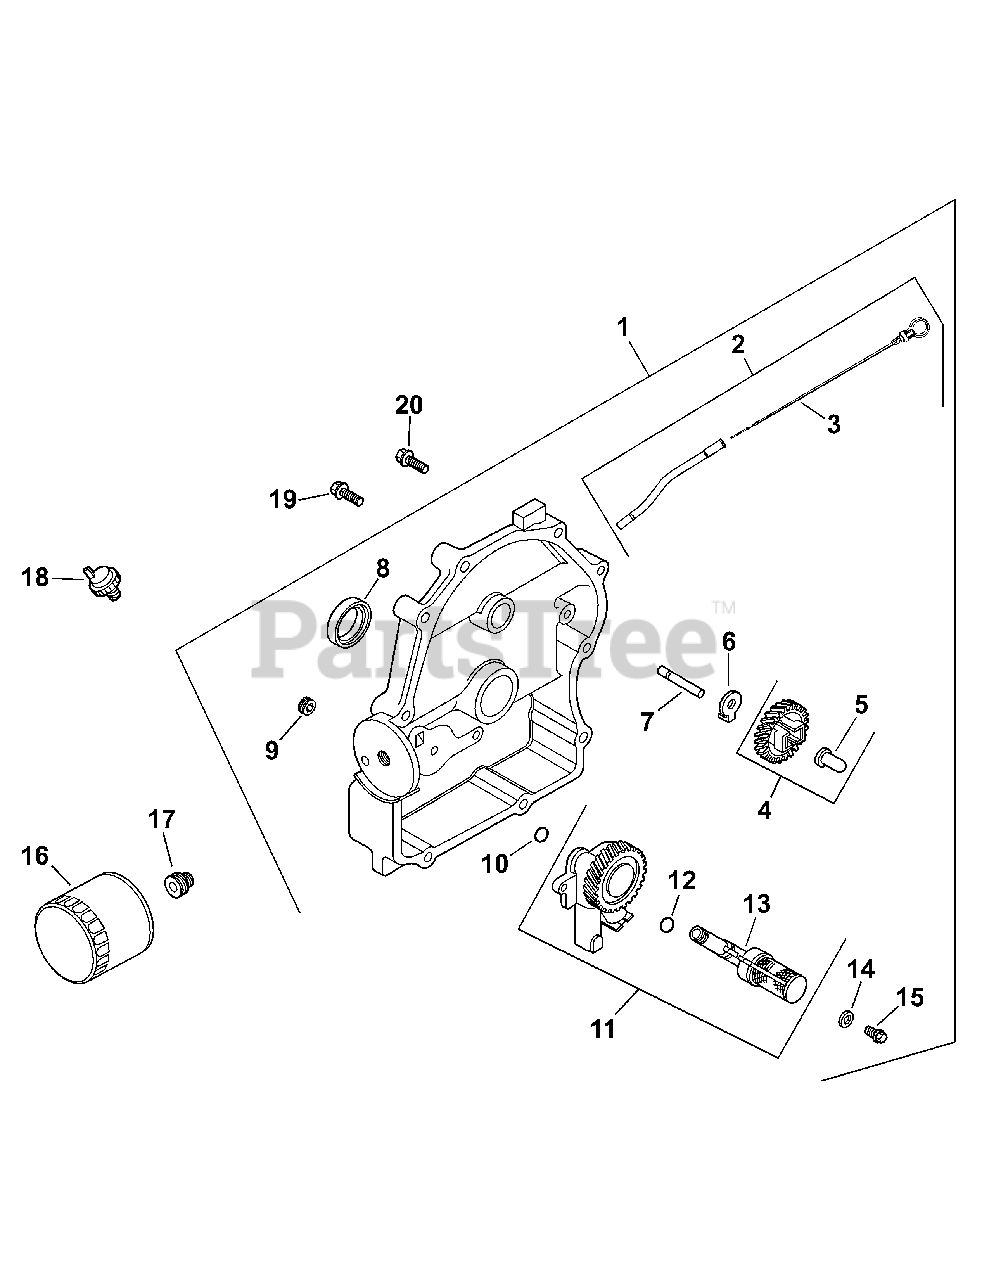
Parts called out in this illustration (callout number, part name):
1	Plate, closure assembly (Includes 2-15)
2	Kit, tube w/dipstick (Includes 3)
4	Kit, governor gear (Includes 5)
5	Pin, governor regulating
7	Shaft, governor gear
8	Seal, oil (PTO end)
9	Plug, pipe 1/8" (2)
11	Oil pump assembly (Includes 12,13)
12	O-Ring, oil pick-up
13	Pick-up, oil
14	Washer, plain 6 mm (2)
15	Screw, hex. flange M6x1.0x25 (2)
16	Filter, oil
17	Nipple, oil filter
18	Switch, pressure
19	Screw, hex. flange M8x1.25x45 (9)
20	Screw, hex. flange M8x1.25x45
